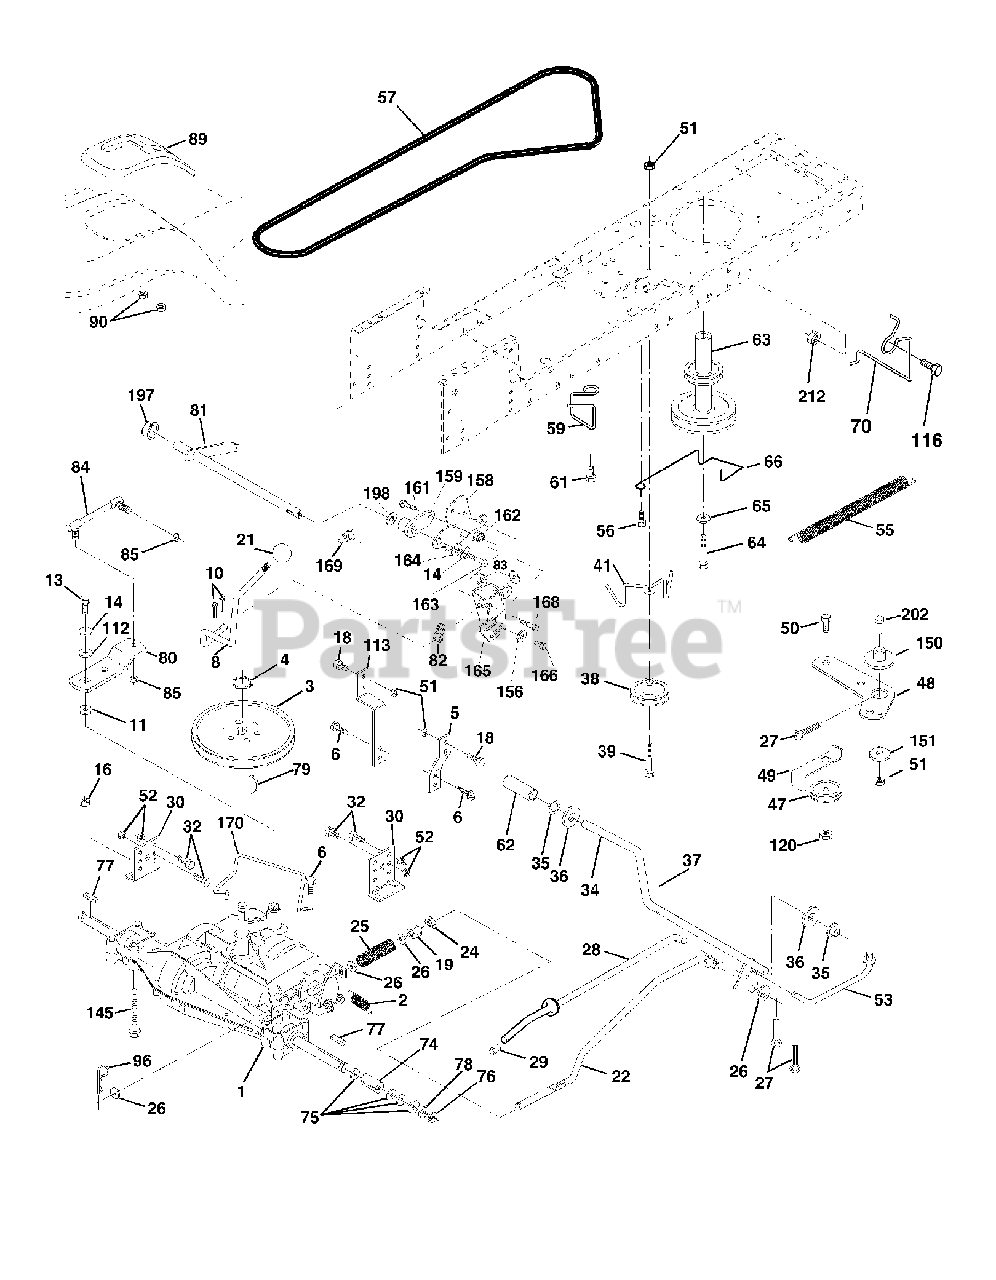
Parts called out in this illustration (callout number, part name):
2	SPRING,BRAKE RETURN
3	PULLEY TRANS
4	RETAINING RING LT
5	STRAP TORQUE
6	SCREW 5/16"
8	ROD.SHIFT.FENDER.ADJ.LT.CRD
10	PIN COTTER
11	WASH-SHFT PLT LT
14	LOCKWASHER
16	NUT.71038.31-18.HEX.NYLOCK
19	NUT
21	KNOB.DELUXE.(PISTOL.GRIP).BLAC
22	ROD BRAKE
24	NUT
25	SPRING ROD LT
27	COTTER PIN
28	ROD, PARKING BRAKE
29	PLUNGER CAP
30	BRKT, TRNSXLE MNT 20"
32	BOLT
34	SHAFT, FOOT PEDAL
35	BEARING.NYLON
36	WASHER LT
38	PULLEY IDLER COMPOSITE
41	KEEPER, BELT IDLER
47	Idler Pulley
48	BELLCRANK, CLUTCH
49	RETAIN BELT
50	Hex Bolt
51	LOCKNUT
52	LOCKNUT
55	SPRING, RETURN LT
56	SCREW.3/8-16
57	Ground Drive Belt, 95.25
59	KEEPER, BELT CENTER
61	SCREW 3/8-16X.875
63	ENGINE PULLEY
65	LOCKWASHER
66	KEEPER BELT ENGINE
70	KEEPER BELT ENG
74	SPACER AXLE
76	E-RING LT
77	SQUARE KEY
79	KEY.WOODRUFF
80	ARM SHIFT
81	SHAFT ASM CROSS TAPERED PMST/2
82	SPRING,TORSION
83	WASHER
84	LINK.TRANSAXLE.PMST/DANA.20"
85	NUT LOCK CENTER 1/4 -28 FNTHD
90	NUT.PUSH.3/16
112	WASHER LT
113	STRAP TORQUE LH LT
120	NUT LOCK FLG 3/8-16 UNC
150	SPACER, RETAINER
151	WASHER 12/32X2X10GA
156	WASHER.SRRTD.5/16
158	BRACKET
161	BOLT
162	NUT.CROWNLOCK.1/4
165	RP BRACKET
168	BOLT.SHOULDER.5/16-18X
169	PLATE.FASTENING.CROSS.SHAFT
170	KEEPER BELT T/A
197	NYLINER SNAP 5/8" ID
198	WASHER.NYL.7/8IDX.105"HYD CR
202	BOLT.3/8-16X1.50
212	Flange Hex Lock Nut, 3/8-16
